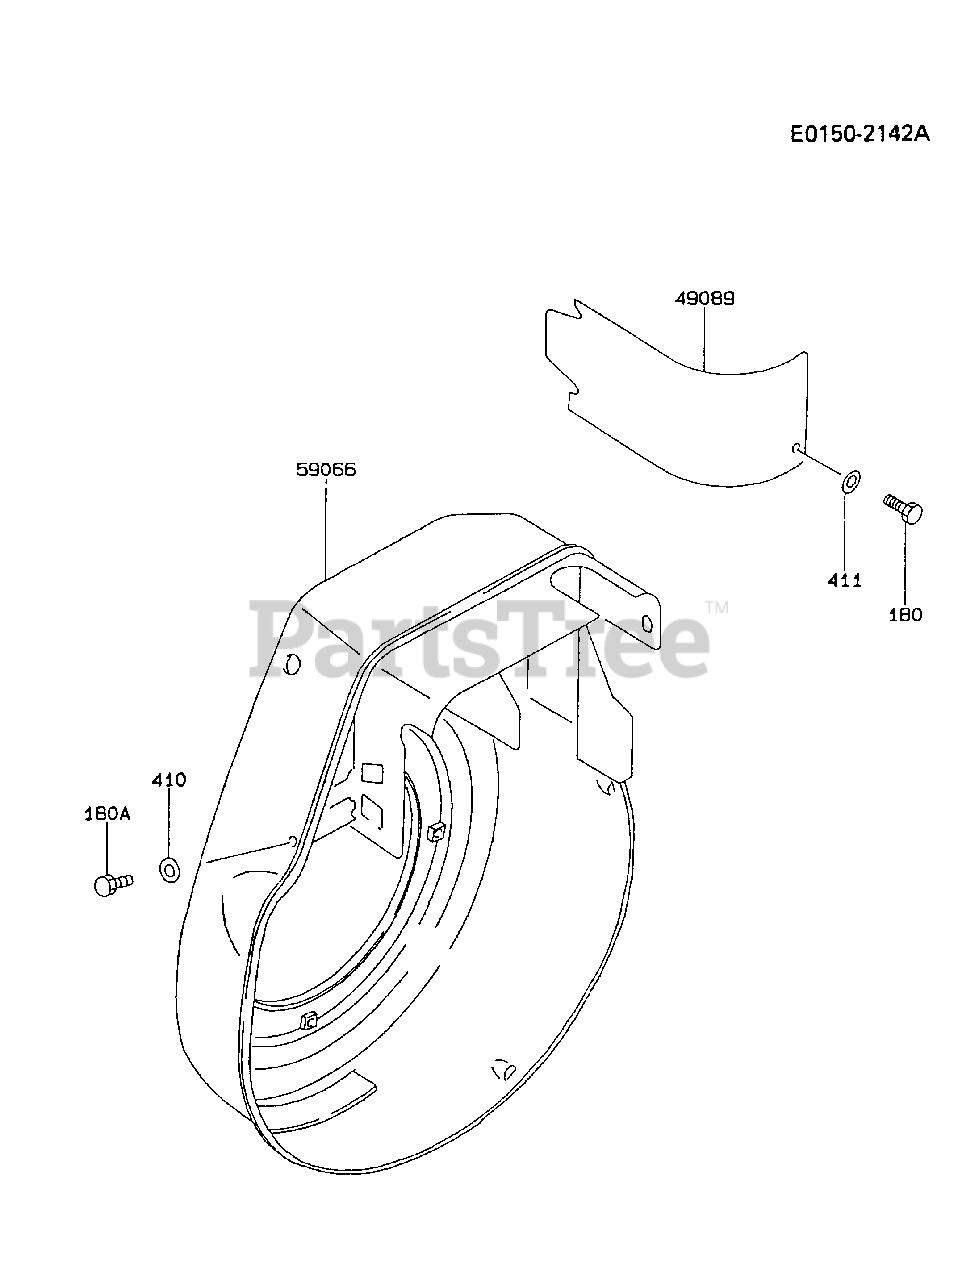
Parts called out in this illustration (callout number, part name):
180	BOLT-UPSET-WS
180A	BOLT-UPSET-WS
410	W-PLAIN-S
411	WASHER-PLAIN
49089	SHROUD-ENGINE
